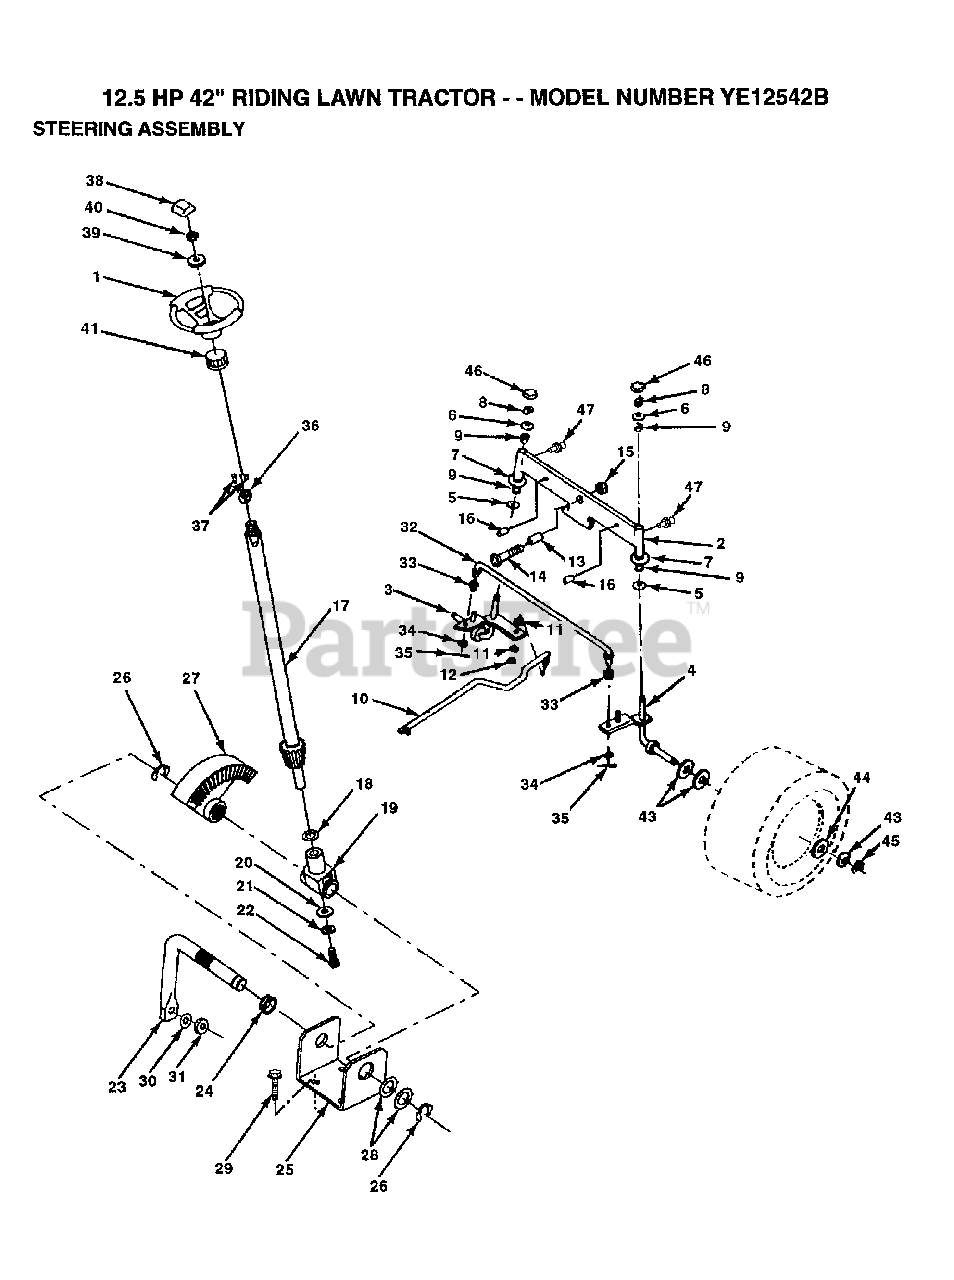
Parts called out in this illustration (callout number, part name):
3	SPINDLE LH
4	SPINDLE RH
5	WASHER .T
6	WASHER
7	WASHER
8	RING
9	COL. SRTG. BEAR.
11	LOCKWASHER
13	BEARING
14	BOLT HEX 5/8-11
16	AXLE PIN
17	STEERING SHAFT
18	THRUST WASHER
19	SUPPORT.SHAFT
21	LOCKWASHER
22	"SCREW,SPECIAL"
24	NYLINER T
25	"BRKT,STEERING"
26	RING
28	WASHER .T
29	SCREW
30	LOCKWASHER
32	TIE ROD
33	BUSHING.DRAGLINK
34	WASHER
35	COTTER PIN
38	INSERT STEERING
39	WASHER
41	ADAPTER LT
43	WASHER
44	WASHER
45	RING
46	CAP
47	ZERK M
